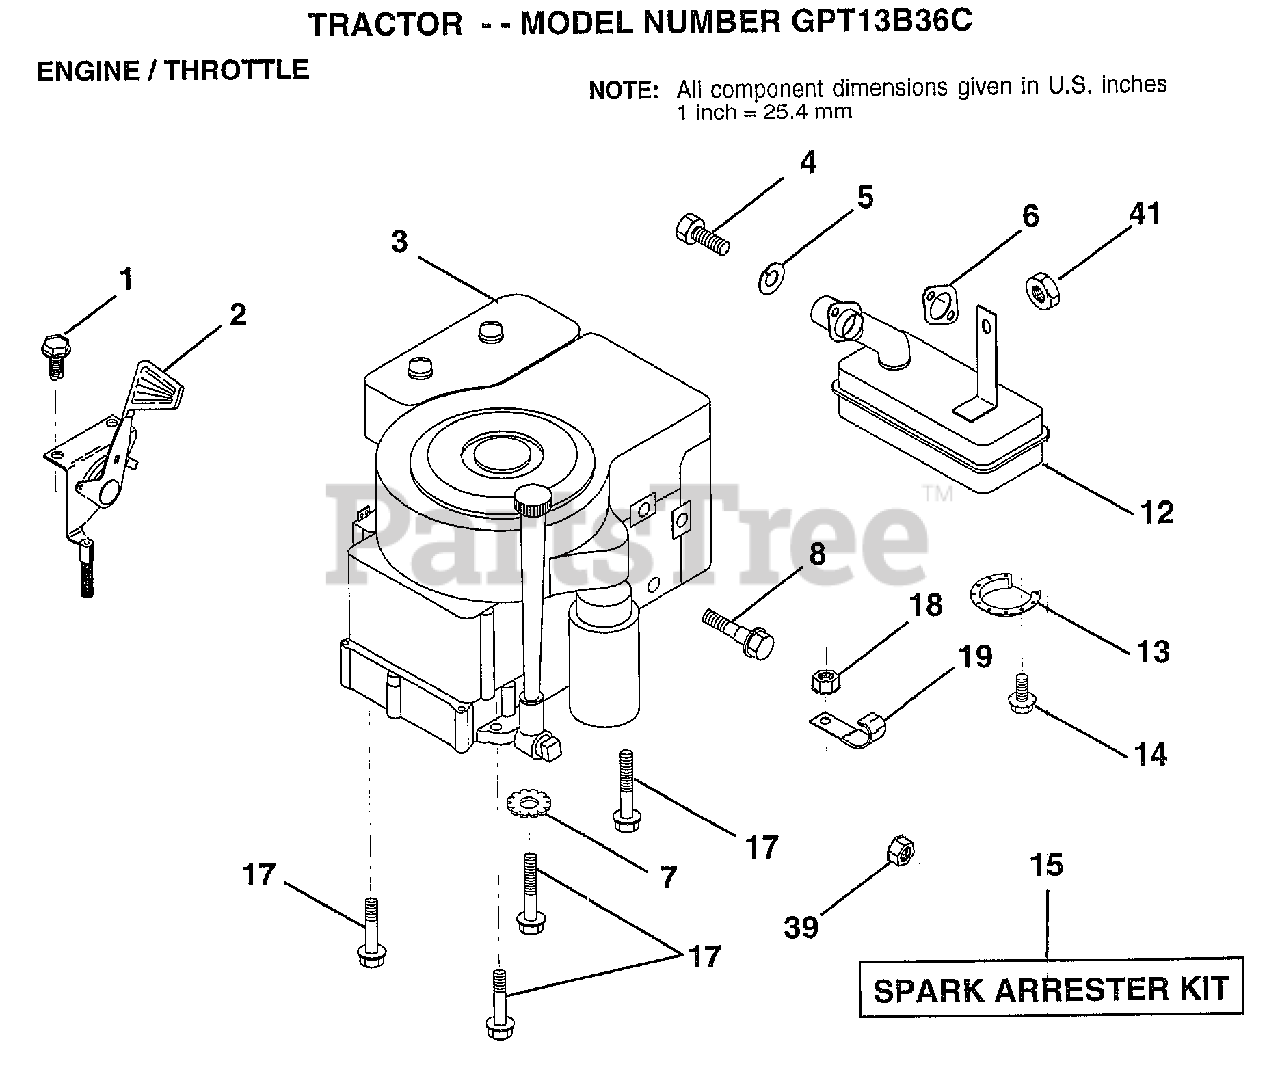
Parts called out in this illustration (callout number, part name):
1	SCREW.1/4-20X1/2
2	"CONTROL,THROTTLE"
4	SCREW HEX HD CAP
5	LOCKWASHER
7	LOCKWASHER
8	SHOULDER BOLT ST
12	MUFFLER-TECH 13HP
13	DEFLECTOR.222573
17	SCREW LT
18	NUT
19	CLIP T
39	NUT
41	"NUT HEX,LOCK,FLAN"
